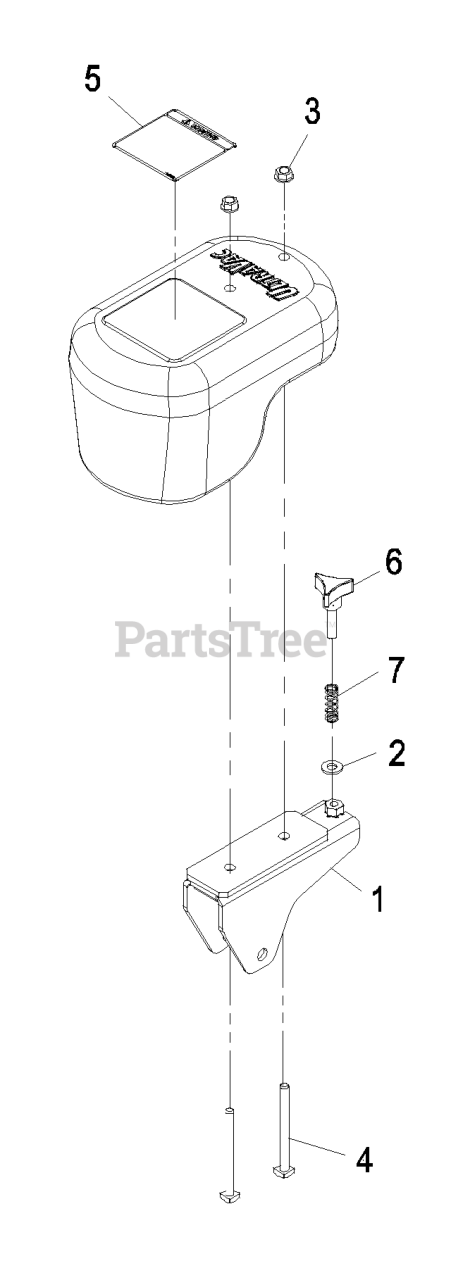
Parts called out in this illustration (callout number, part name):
1	WLD,CASTER WEIGHT BRACKET
2	WASHER-FLAT
3	NUT-HHF, WHIZ
4	BOLT, SQUARE HEAD YZ
5	DECAL,WEIGHT
